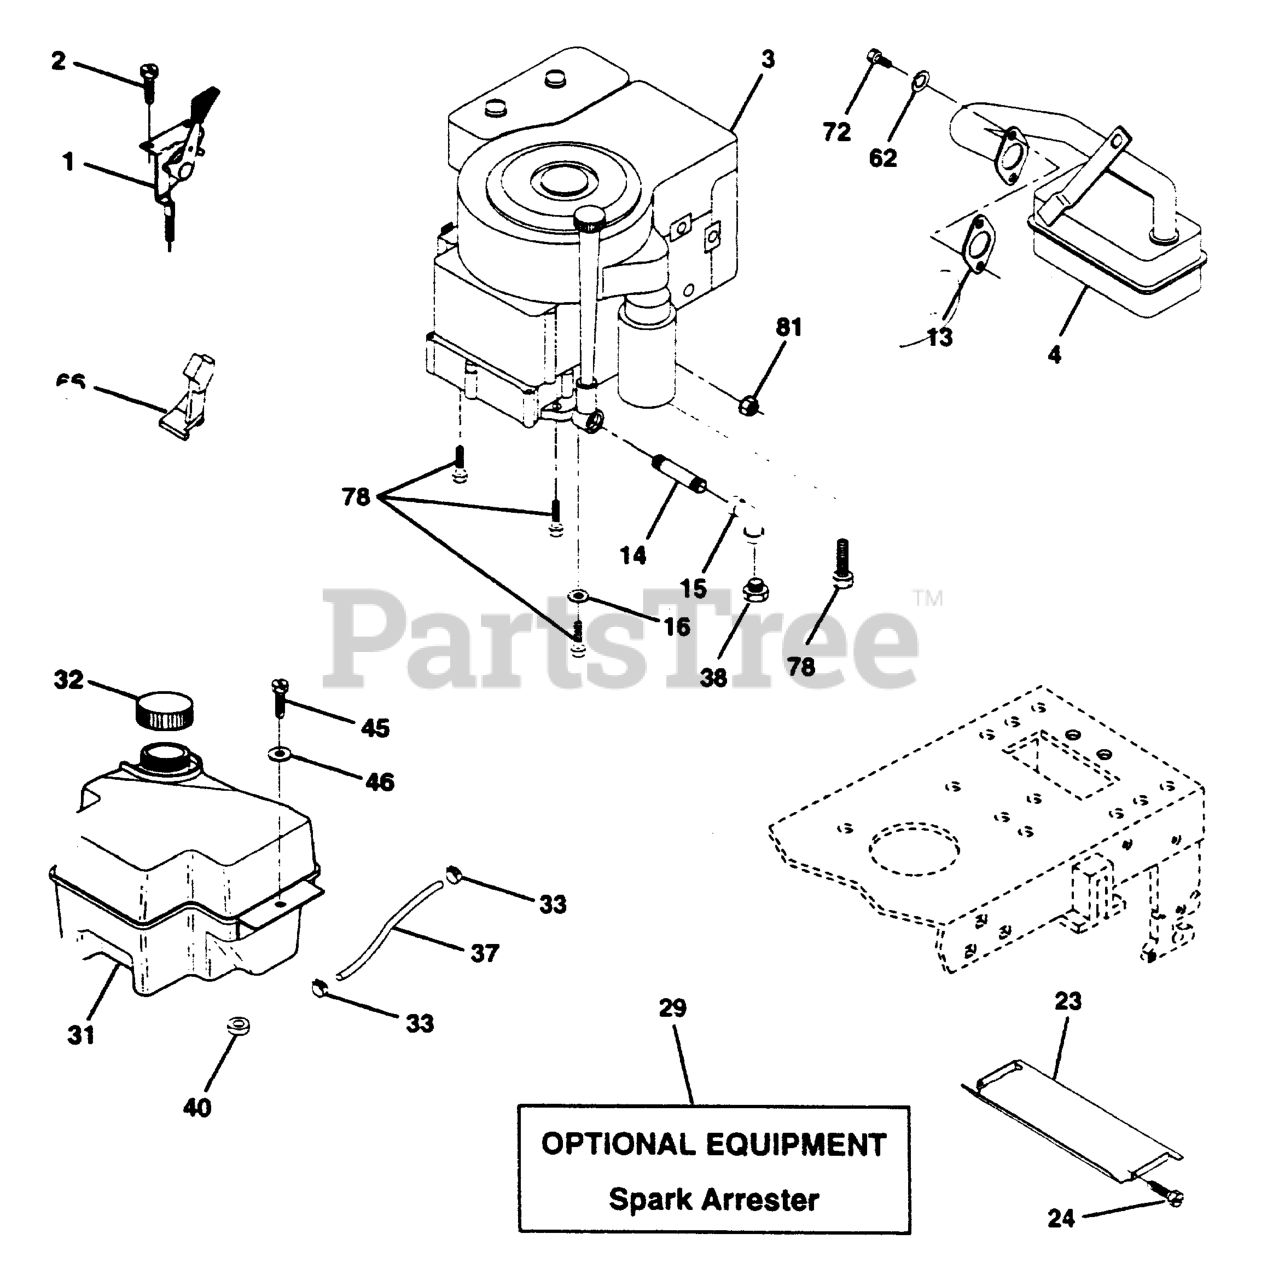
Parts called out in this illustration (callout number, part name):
1	CONTROL
2	SCREW LT
4	MUFFLER.LT.BRIGGS.14HP.IC/OHV
13	GASKET.ENG.1.313 ID.TIN PLATED
14	Nipple Pipe 3/8 Npt X 3-1/2
15	ELBOW
16	LOCKWASHER
23	HEAT SHIELD
29	KIT.SPARK ARRESTOR 794945 B&S
31	FUEL TANK
32	FUEL CAP
33	HOSE CLAMP
40	BUSHING.SNAP.NYL.BLK.
45	SCREW HEX CRT
62	WASHER.LOCK.HVY.HLCL.SPR.5/16
66	STOP THROTTLE
72	SCREW
78	SCREW
80	Bolt, Hex Head, Fin. 5/16-18 x 1/2
81	NUT FLANGE 1/4-20 STARTER NUT
